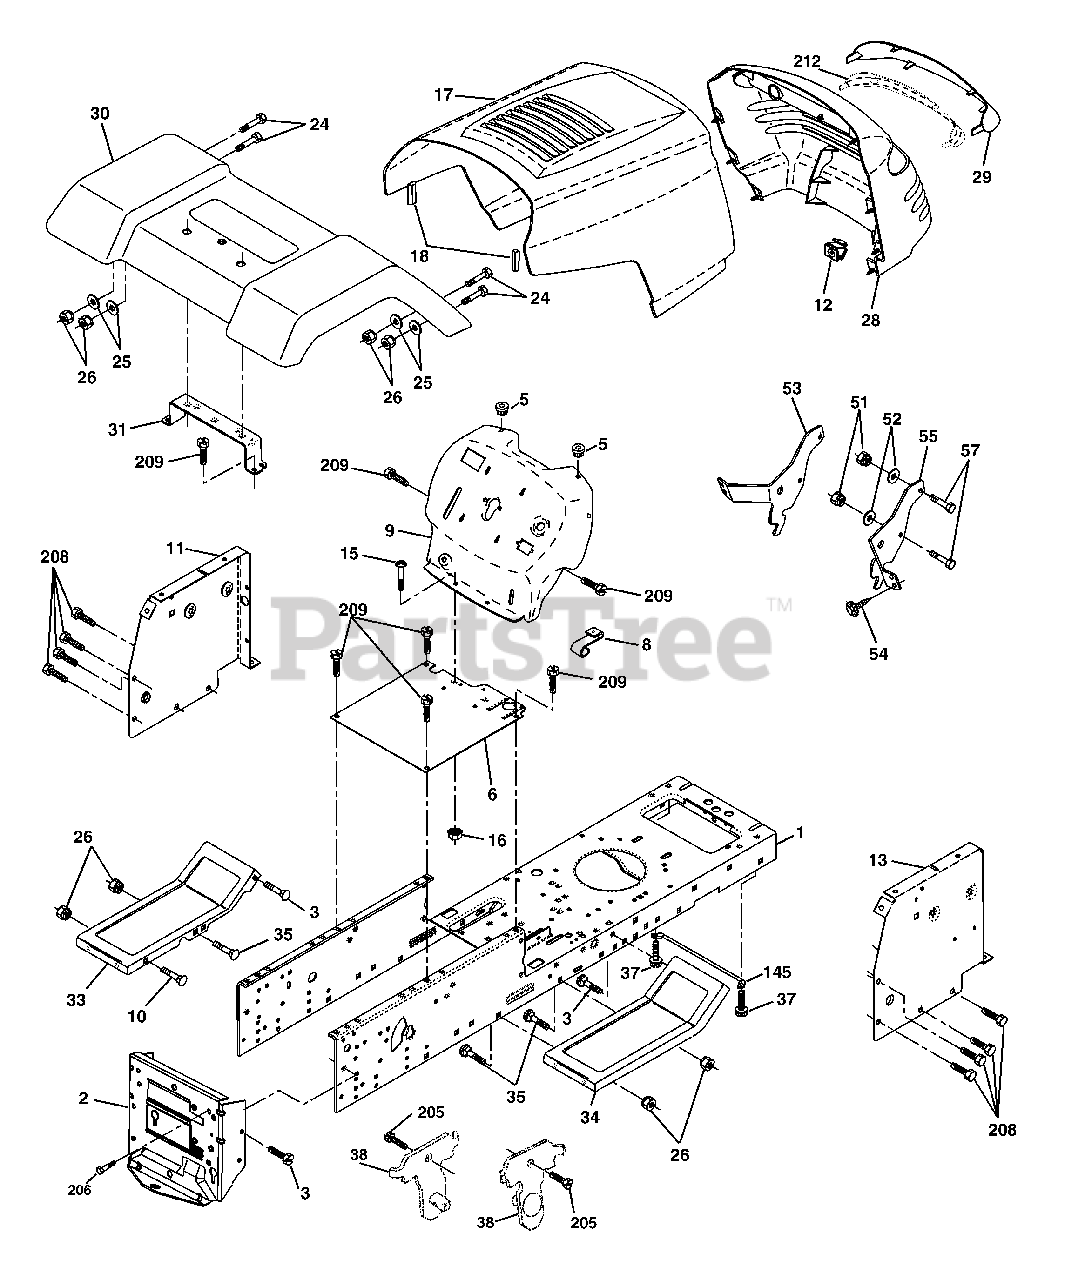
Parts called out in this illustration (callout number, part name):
1	Chassis
2	Drawbar, Stretch
3	Screw 3/8-16 x 3/4
5	Bumper, Hood/Dash
6	Saddle Silkscreen
8	Clip Retainer Slide-On
9	Dash
10	Bolt, Carriage 3/8-16 x 1
11	Panel Dash LH
12	Clip Tinnerman Grille P.L
13	Panel Slkscr Dash RH
15	Screw Mach TRHD 5/16-18 Unc x 3/4
16	Nut Keps 5/16-18 Unc
17	Hood
18	Bumper Hood
24	Bolt Fin Hex 3/8-16 Unc x 1 Gr. 5
25	Washer 13/32 x 13/16 x 12 Ga.
26	Nut Lock Hex w/Ins 3/8-16 Unc
28	Grille/Lens Asm.
29	Lens Grille Private Label
30	Fender
31	Bracket Fender Repl 109873X
33	Footrest Pnt LH
34	Footrest Pnt RH
35	Bolt Rdhd Sht Sqnk 3/8-16 x 3/4
37	Screw Thdrol 5/16-18 x 1/2 TYT
38	Bracket Asm. Pivot Mower
51	Nut Lock W/Insert 1/4-20unc
52	Washer 9/32 x 7/8 x 16 Ga.
53	Bracket Grille Lh
54	Screw Hex 8-18 x 7/8
55	Bracket Grille Rh
57	Bolt Fin Hex 1/4-20 Unc x .75
145	Rod Pivot Chassis/Hood
205	Screw Thdrol 3/8-16 x 1/2
206	Bolt Shoulder 5/16-18
208	Screw Thdrol 3/8-16 x 1/2
209	Screw Hex Wsh Thdrol 3/8-16
212	Insert Lens Reflect
